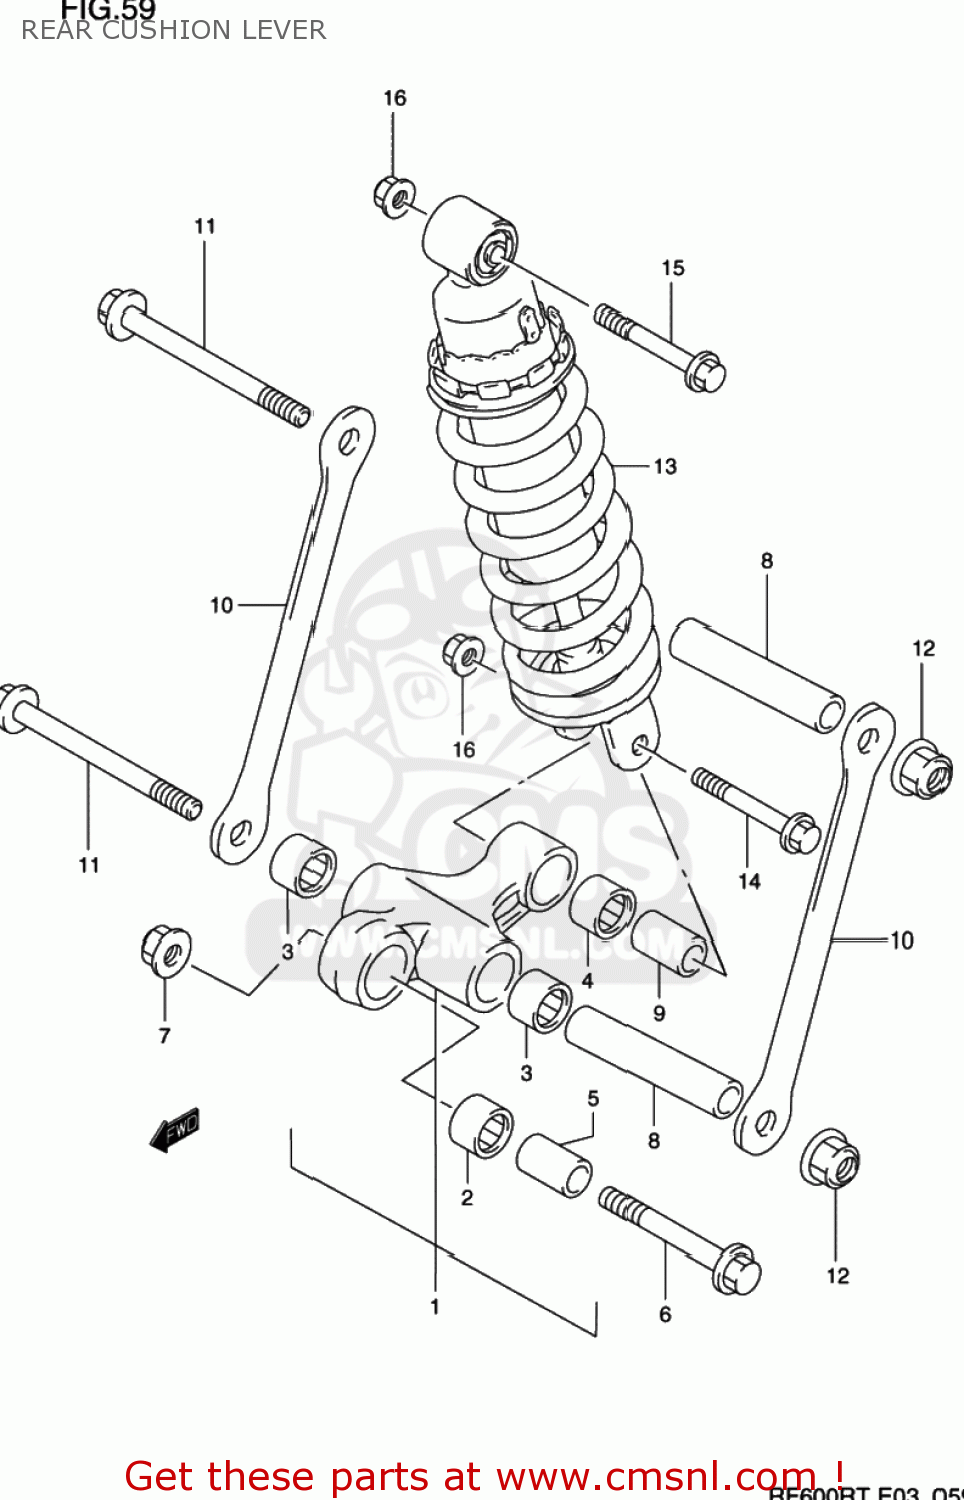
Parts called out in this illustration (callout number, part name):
1	LEVER SET,RR CUSHION
2	BEARING(20X27X26)
3	BEARING(17X24X25)
4	BEARING(17X24X26)
5	SPACER,REAR CUSHION LEVER
6	BOLT,CUSHION LEVER FR
7	NUT 12MM
8	SPACER(12X17X85)
9	SPACER,RR CUSHION LEVER
10	ROD,RR CUSHION LEVER
11	BOLT(12X115)
12	NUT 12MM
13	ABSORBER ASSY,RR SHOCK
14	BOLT(10X58)
15	BOLT(10X50)
16	NUT
